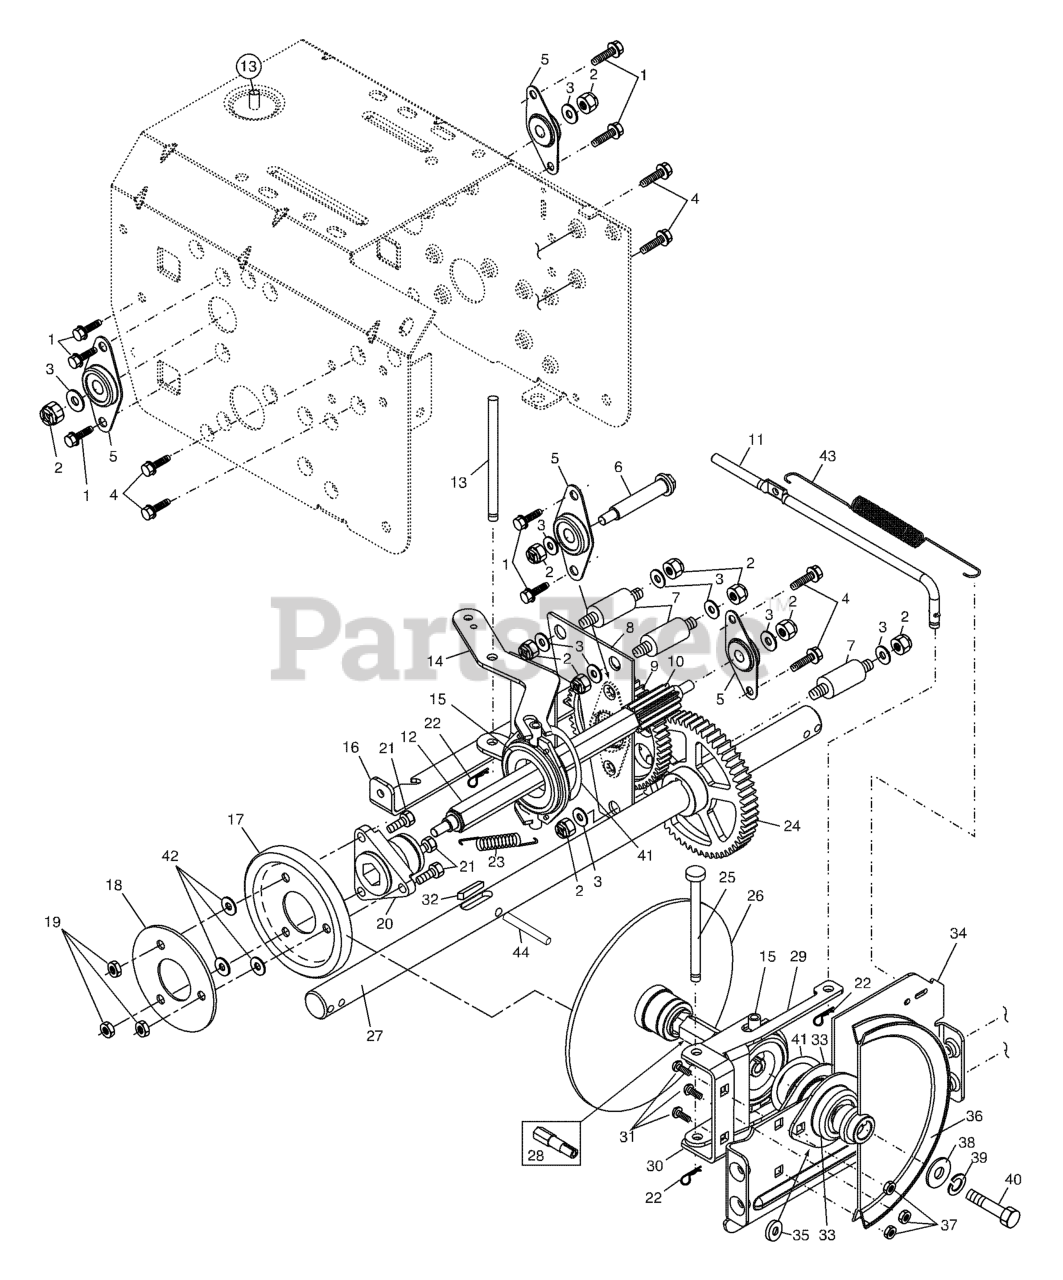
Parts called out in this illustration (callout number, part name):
2	NUT.71038.31-18.HEX.NYLOCK
3	WASHER.20X8.5
4	Screw, Hex Head 5/16-18 x 1/2
5	BEARING, FLANGE
6	SHAFT, AUXILIARY
7	SPACER, PLATE
8	AUXILLARY PLATE
9	GEAR, INTERMEDIATE
10	GEAR, PINION
11	ROD.CLUTCH.YELLOW.ZINC
12	SHAFT.HEX.LONG
13	PIN, PIVOT
14	LEVER, SPEED CONTROL
15	TRUNNION BEARING ASSY
16	BRACKET, PIVOT, SHIFT
17	RING, RUBBER WHEEL
18	PLATE, RUBBER WHEEL
19	NUT.CENTERLOCK.5/16-
20	HUB, RUBBER WHEEL
21	BOLT
22	RETAINER CLIP PM
23	SPRING, BIAS
24	GEAR, AXLE (58T)
25	PIN, PIVOT LEVER
26	PLATE ASSEMBLY, DRIVE
27	SHAFT.AXLE.16".POWER.STEER.SNO
28	SHAFT, SHORT HEX
29	LEVER.SHIFTER.PLATE.BLACK
30	BRACKET, SHIFTER SUPPORT
31	BOLT
32	KEY
33	BEARING FLANGE
34	PLATE.DRIVE.MOUNTING.BLACK
35	SPACER, BEARING
36	PULLEY.TRACTION.7.75
37	NUT.FLANGE.5/16
38	WASHER, FLAT
39	WASHER.LOCK.HVY.HLCL.SPR.5/16
40	Screw, Hex Head 5/16-18 x 3/4
41	RETAINING RING (2 2)(3 2)
42	WASHER.20X8.5
43	SPRING.RETURN
44	PIN.ROLL.3/16
